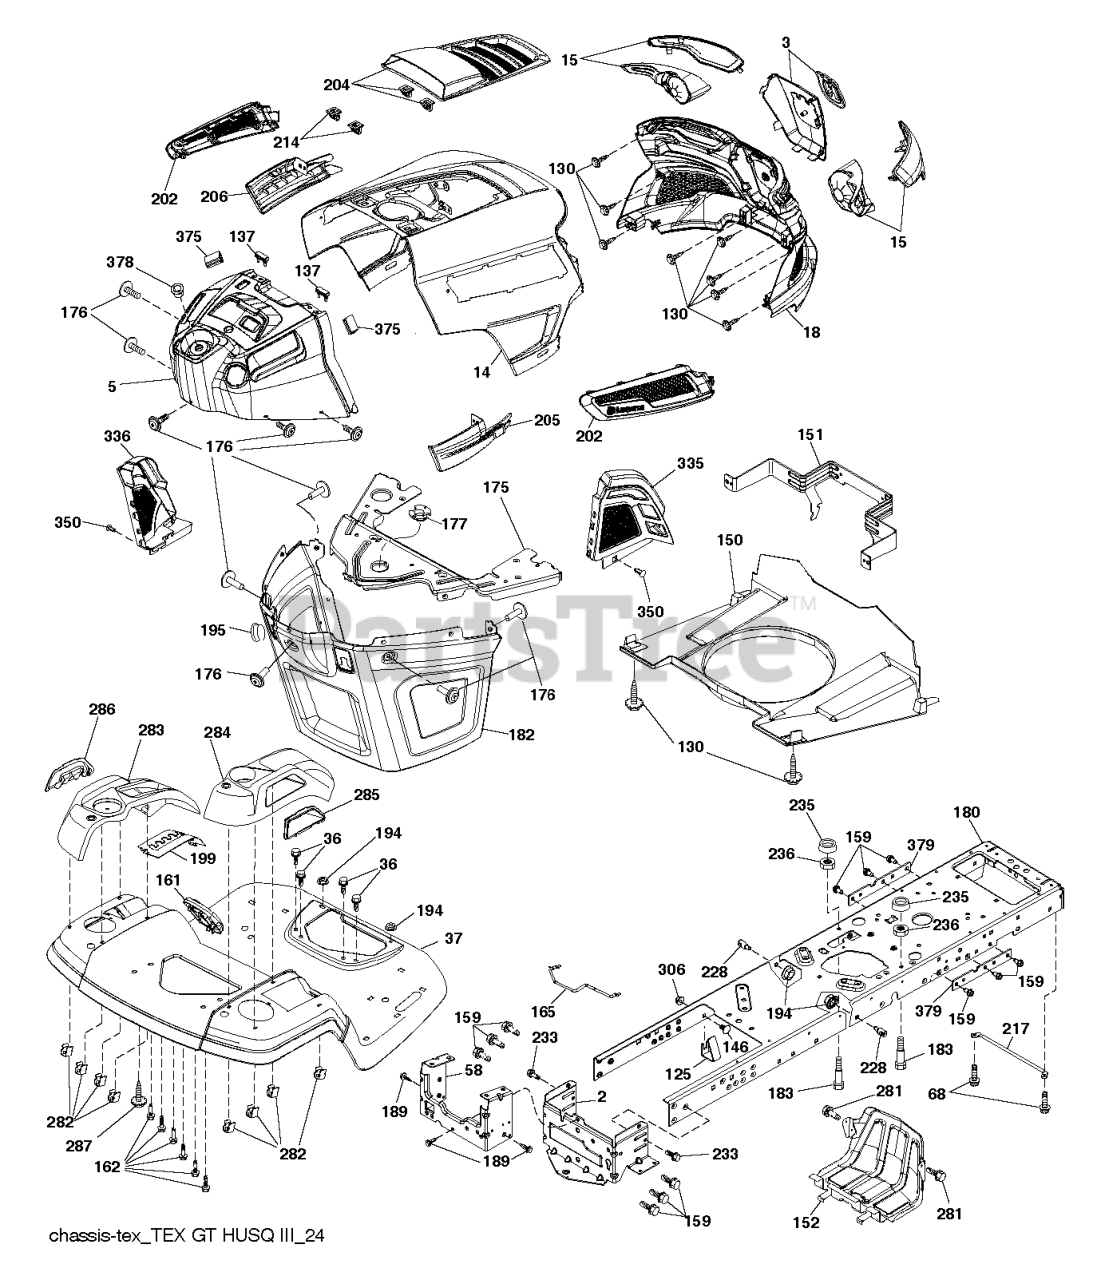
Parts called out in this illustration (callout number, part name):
2	DRAWBAR.LOWER.2PC.18/22
5	DASH.UPR.GT2.SM.PTO.MC.HR.498
14	HOOD.ASM.HUSQVARNA.GT.TEX.ORAN
15	Service Kit
36	SCREW 5/16"
37	FENDER.TLT.FS.W/CPH/FW/RSF.668
58	DRAWBAR.UPPER.2PC,LRG.FENDER
125	CLIP.FUEL.LINE
137	BUMPER DASH
146	BOLT.RDHD.SHT.SQNK.3/8-16X5/8
150	AIR.DUCT.GTV.BLACK
151	BRACKET.PIVOT.HOOD.GT.HUSQ.II
152	SHIELD.BROWNING.PNT.GT.V2
159	SCREW, 3/8-16X3/4
161	WINDOW.FUEL.LT.HUSQ.TEX.498
165	SUPPORT.TANK.REAR.B/TE
175	PLATE.PNT.CROSSMEMBER.HUSQ/PRE
176	SCREW.#10-24X5/8.RN.QU
177	BUSHING STEERING
180	CHASSIS.LT/GT.BOLTED
182	DASH.LOWER.COMMON.12V.ADAPTOR
189	SCREW
195	PLUG.HOLE.DASH.LOWER.12V.BLK
199	PLATE.DECK.LIFT.HUSQVARNA.GT
202	Vents
205	SIDE.TRIM.RH.GT.HUSQ.II
206	SIDE.TRIM.LH.GT.HUSQ.II.GRAY
214	CLIP.RETAINER.TINNER.
217	ROD.PIVOT.HOOD
228	STUD.W/"D"ANTI-ROTATION
233	BOLT.SHOULDER
236	NUT.CENTERLOCK.5/16-
281	SCREW 3/8-16X1
282	CLIP.RETAINER.CONSOLE.LT.HUSQ
283	CONSOLE.DECK.LIFT.R.SDFL.HUSQ
284	CONCOLE.CNTRL.PDL.HUSQ.LT.498
285	CONSOLE INSERT RH
286	CONSOLE.INSRT.LH.HUSQ.LT.BLACK
287	SCREW 1/4X20
306	NUT LOCK FLG 3/8-16 UNC
335	COVER.LOWER.DASH.RH.BLACK
336	COVER-LH.LOWER.DASH.GT2.BLACK
350	CLIP.X-MAS.TREE
375	BUMPER CLIP-ON. DASH 1"
378	BUSHING FLANGE; PLASTIC
379	CHASSIS.PLATE.REINFORCEMNT.431
